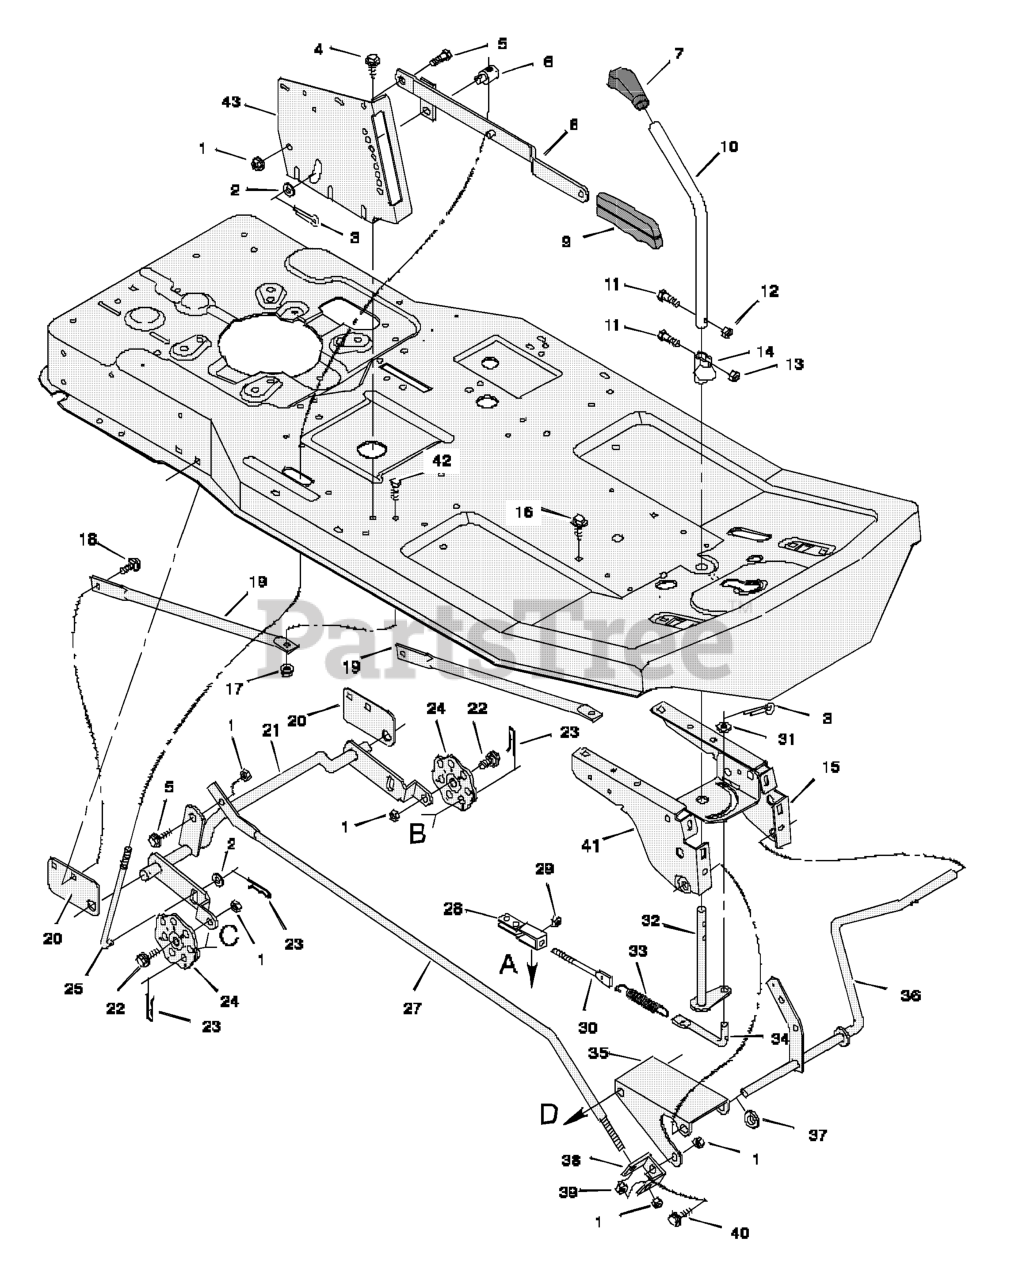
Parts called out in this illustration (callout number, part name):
1	Locknut, Flange
2	Washer
3	Pin, Cotter
5	Bolt, Shoulder
6	Nut, Adjusting
7	Grip, Blade Control
8	Lever Assembly, Lift
9	Grip, Lift Lever
10	Attachment, Clutch
11	Bolt, Hex
12	Locknut
13	Locknut, Flange
14	Cam, Blade Control
15	Plate, Left Suspension
17	Locknut, Flange
18	Bolt, Carriage
19	Strut, Frame
20	Plate, Mounting
21	Rod Assembly, Rear Suspension
22	Bolt, Shoulder
23	Pin, Hair
24	Plate, Adjusting
25	Rod, Lifter
27	Rod, Suspension
29	Nut, Hex
30	Link, Blade Drive
32	Rod and Arm Assembly
33	Spring, Extension
34	Link, Front Deck
35	Bracket, Front Suspension
36	Lever, Pedal
37	Washer
38	Clevis
39	Locknut, Hex
40	Bolt, Shoulder
41	Plate, Right Suspension
42	Bolt, Hex
43	Plate, Index
